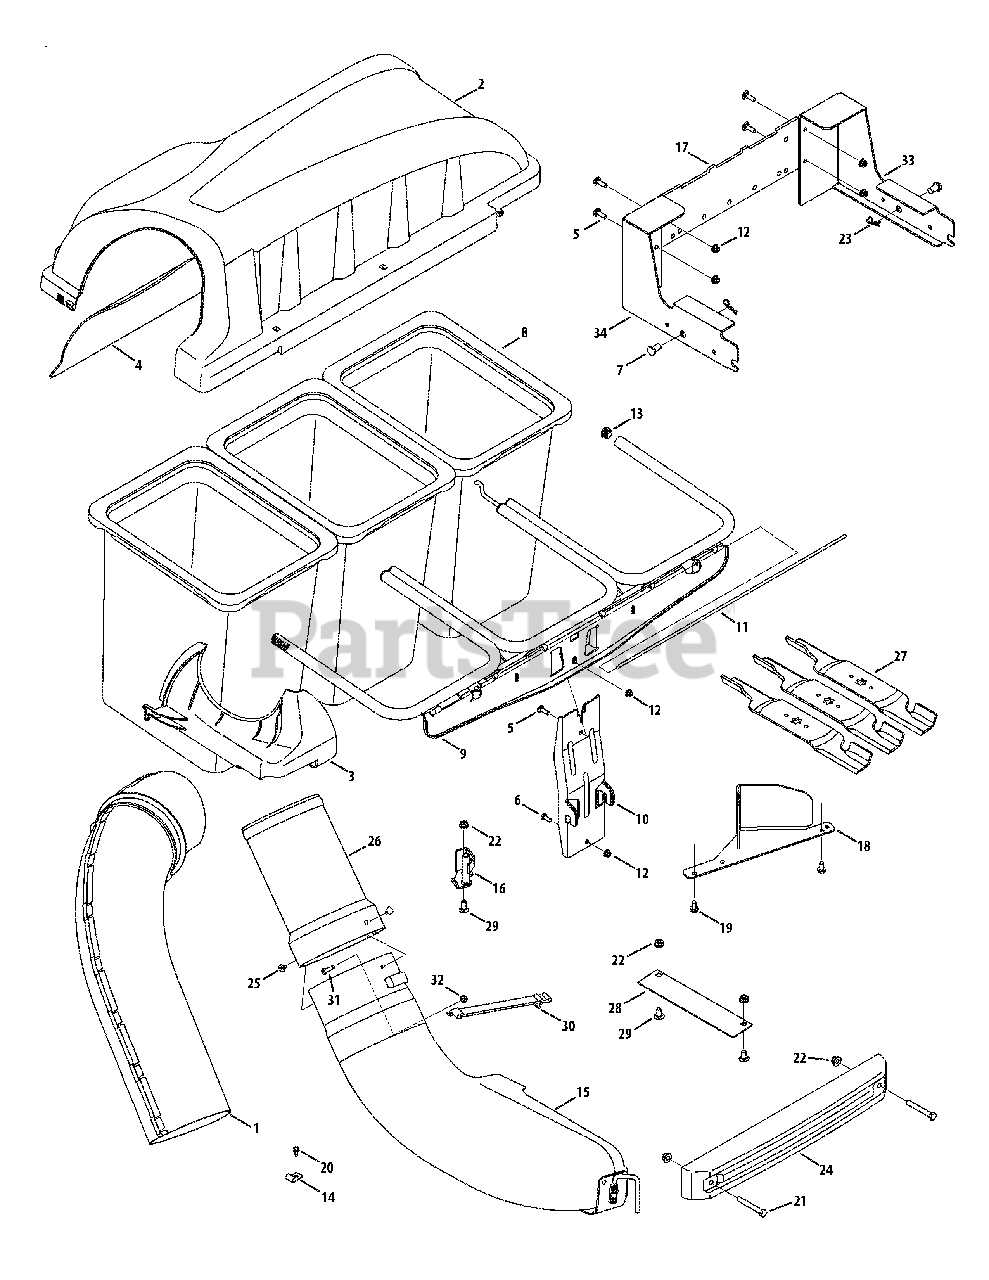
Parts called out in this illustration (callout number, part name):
1	Upper Chute Assembly
2	Triple Bagger Cover Assembly
3	Upper Chute Support
4	Bagger Cover Screen
5	Carriage Screw, 5/16-18 x 1.00"
6	Hex Head Screw, 5/16-18 x .75"
7	Clevis Pin, .50" Dia. x .78 Lg.
8	Grass-bag Assembly
11	Cover Hinge Pin
12	Flange Lock Nut, 5/16-18
14	Retainer Hook
15	Discharge Chute Elbow
16	Chute Stop-Bracket
17	Universal Mounting Bracket
19	Tap Screw, 5/16 - 18 x .750
20	Tap Screw, 1/4 - 20 x .500
21	Hex Head Screw, 3/8 - 16 x 2.75
22	Flange Lock Nut, 3/8 - 16
23	Cotter Pin, .080 x 1.5625 Internal
24	RZT Bagger Weight
25	Ratchet Clip, .250
26	Bagger Chute Adapter, 7 In.
27	Blade, 18.50 Lg., High Lift
28	Chute Discharge Plate
29	Carriage Bolt, 3/8-16 x 1.00
30	Chute Strap
31	Hex Head Screw, 1/4-20 x .75
32	Flange Lock Nut, 1/4 - 20
33	RZT Mounting Bracket, LH
34	RZT Mounting Bracket, RH
